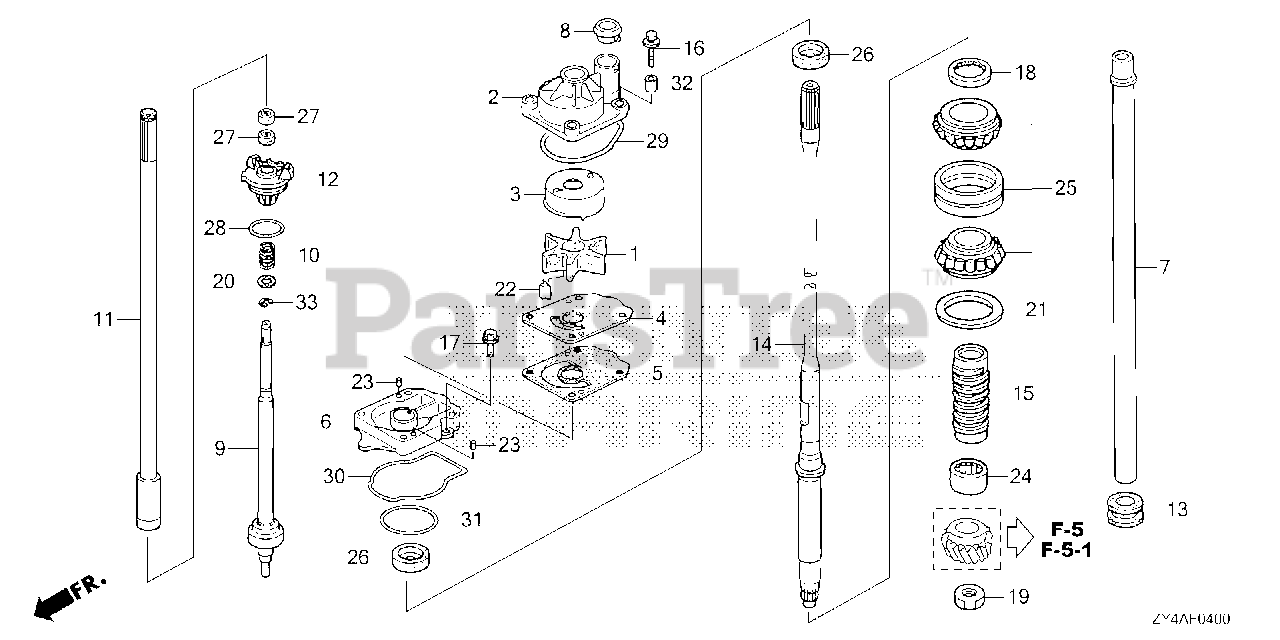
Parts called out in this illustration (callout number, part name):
1	IMPELLER, PUMP
2	HOUSING, IMPELLER
3	LINER, PUMP
4	COVER, IMPELLER
5	GASKET B, IMPELLER
6	HOUSING, WATER PUMP
7	TUBE, WATER (XL)
8	RING, WATER TUBE SEAL
9	ROD, SHIFT (COUNTER ROTATION)
10	SPRING, SHIFT ROD
11	ROD A, SHIFT (XL)
12	HOLDER, SHIFT ROD
13	GROMMET, EXTENSION CASE
14	SHAFT, VERTICAL (XL)
15	SLINGER, OIL
16	BOLT-WASHER (8X60)
17	BOLT, FLANGE (6X16) (SUS)
18	NUT, LOCK (64MM)
19	NUT, HEX. (18MM)
20	WASHER, PLAIN (12MM)
21	SHIM A, GEAR (0.10)
21	SHIM B, GEAR (0.15)
21	SHIM C, GEAR (0.30)
21	SHIM D, GEAR (0.50)
22	KEY, WOODRUFF
23	PIN, DOWEL (6X10)
24	BEARING, NEEDLE (32X46X37)
25	BEARING, TAPER ROLLER (30X62X40)
26	SEAL, WATER (26X42X7)
27	SEAL, WATER (12X21X6)
29	O-RING, WATER PUMP
30	O-RING, WATER PUMP HOUSING
31	O-RING (69.1X2.4)
32	COLLAR, DISTANCE
33	E-RING (10MM)
